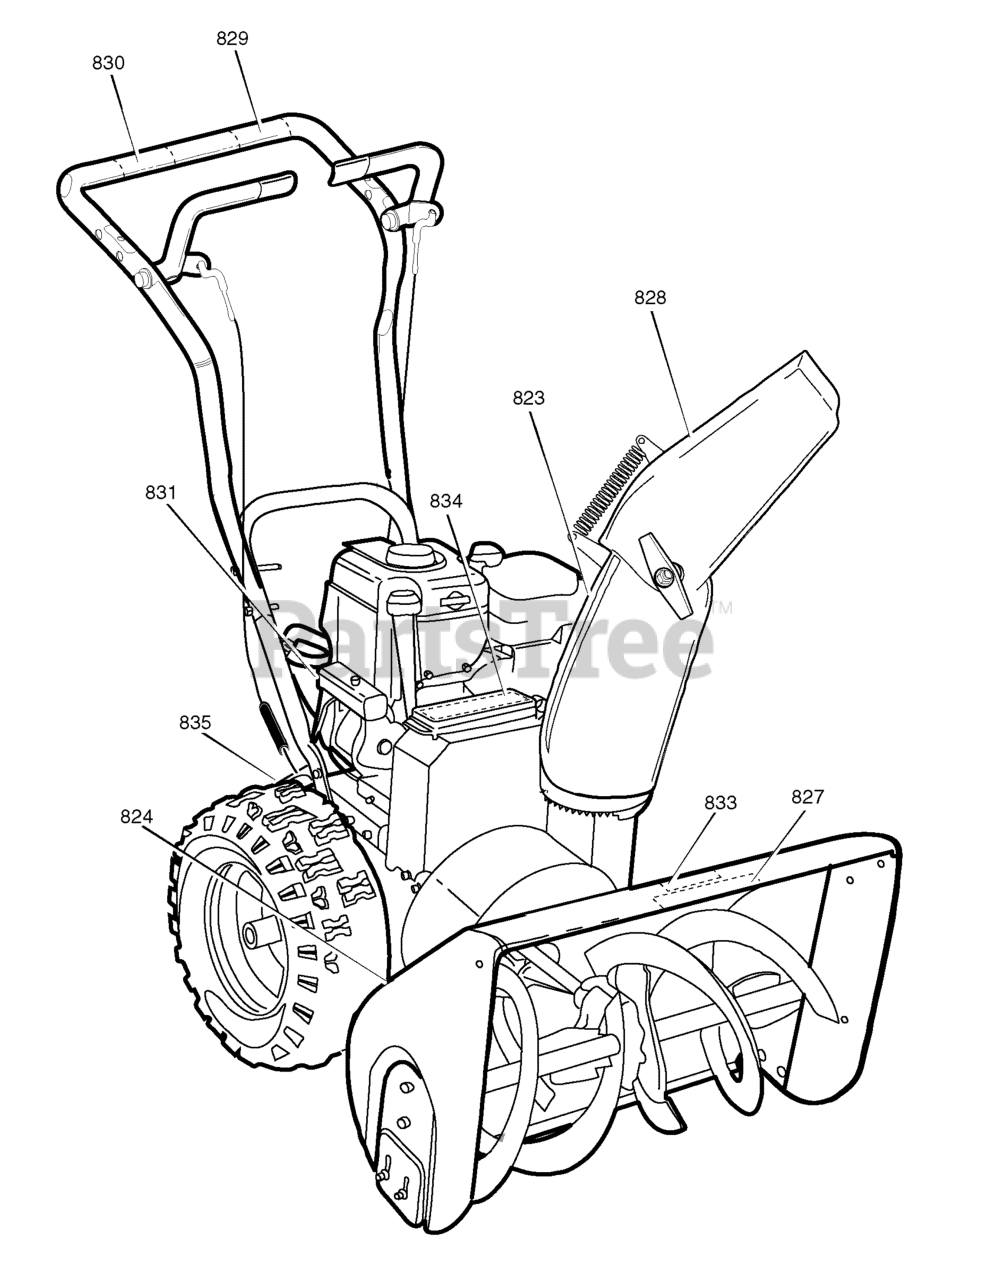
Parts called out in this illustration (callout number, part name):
823	DECAL, DANGER CHUTE HAND
824	DECAL, DANGER FOOT
827	DECAL, 900/24 CRAFTSMAN AUGER
828	DECAL, THROWN OBJECTS
829	DECAL, DRIVE CLUTCH
830	DECAL, AUGER CLUTCH
831	DECAL, GEAR SELECTOR
833	DECAL, CLEAN & CLEAR BRUSH
834	DECAL, TOOLBOX INFORMATION
835	DECAL, ID PLATE
